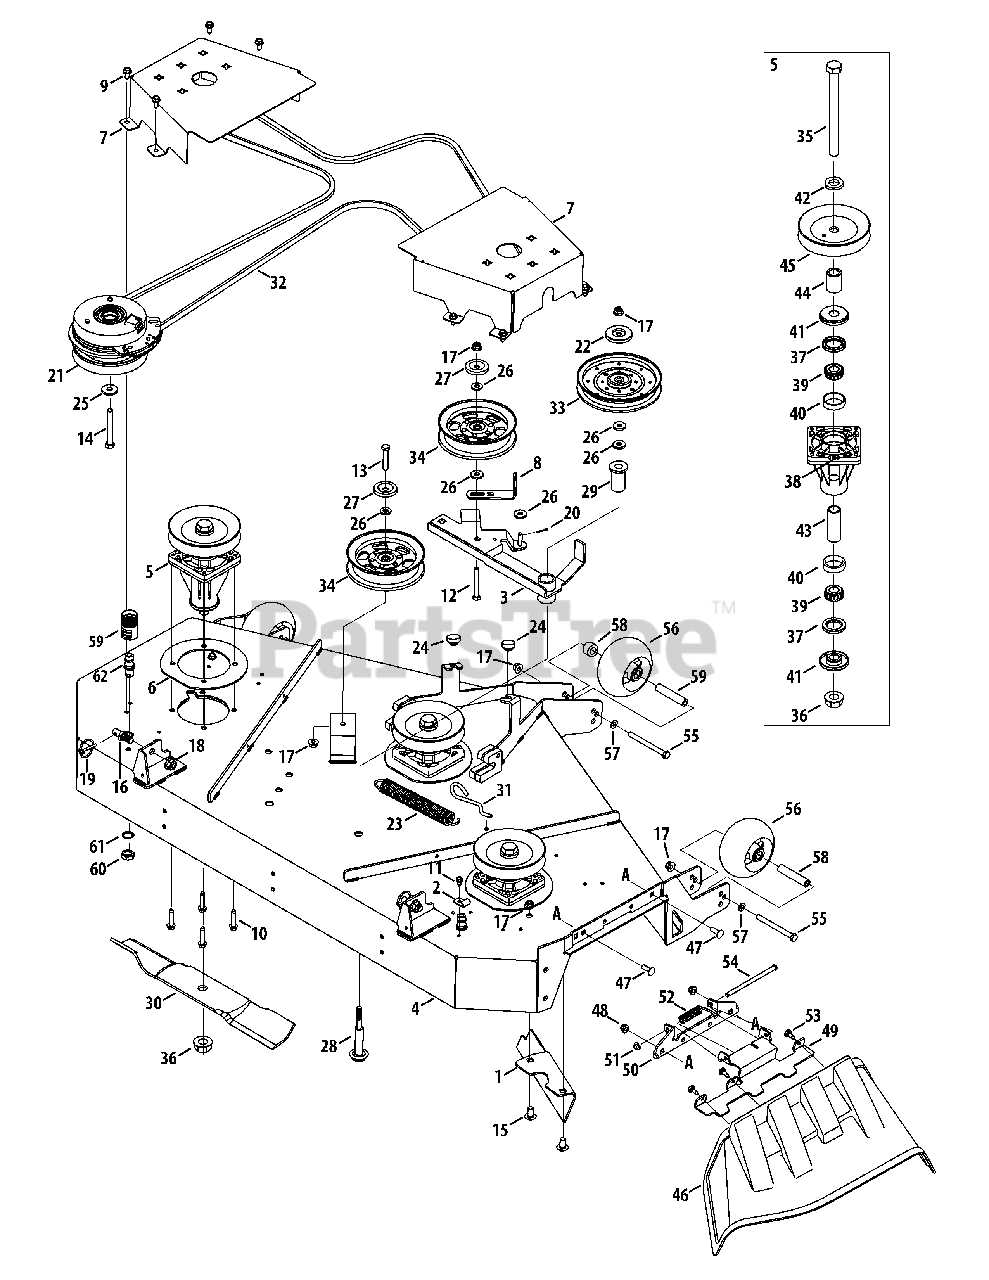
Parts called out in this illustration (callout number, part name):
2	Bracket, Hook Retainer
3	Deck Idler Assembly
4	60" Deck FAB - Yellow
4	60" Deck FAB - Black
5	Spindle Assembly
6	Spindle Reinforcement Plate - Yellow
6	Spindle Reinforcement Plate - Black
7	Belt Cover - Yellow
8	Bracket, Deck Keeper - Black
9	Hex Washer Screw, 5/16-18 x .750
10	Hex Washer Screw, 5/16-18 x 1.50
11	Hex Washer Screw, 1/4-20 x .500
12	Hex Cap Screw, 3/8-16 x 2.50
13	Hex Cap Screw, 3/8-16 x 2.00
14	Screw, 7/16-20 x 3.25
15	Carriage Screw, 3/8-16 x .75
16	Pin, Shoulder Lock, .500
17	Flange Lock Nut, 3/8-16
18	Flange Lock Nut, 1/2-13
19	Pin, Lynch x .1875
20	Cotter Pin 3/32" Dia. x .75 Lg.
21	Electric PTO Clutch
22	Pulley Cap
23	Extension Spring, 1.25 OD x 1.751
24	Rubber Bumper, 1.00 x .313
25	Flat Washer, .450 x 1.25 x .164
26	Flat Washer, .406 x .875 x .105
27	Pulley Cap
28	Shoulder Boult, .625 x 2.12, 3/8-16
29	Shoulder Spacer, 1.055 x .627 x 2.292
30	Blade, 21.00
30	Blade, Med-Lift Extreme
30	Blade, High-Lift Extreme
31	Deck Spring Rod
33	Idler Pulley, 6.00 Dia
34	Idler Pulley, 5.00 Dia.
35	Hex Cap Screw, 3/4-16 x 8.25
36	Nut, 3/4-16, Flangelock
38	Grease Fitting
39	Cone Bearing
40	Cup Bearing
41	Spindle Spacer
42	Spacer, .812 ID x .218 LG
43	Spacer, .78 x 1.00 x 2.895
44	Spacer, .792 x 1.20 x 1.628
45	V-Type Pulley
46	Discharge Chute Assembly
47	Carriage Bolt, 5/16-18 x 1.00
48	Flange Lock Nut, 5/16-18
49	Chute Bracket
51	Push Cap
52	Torsion Spring
53	Shoulder Screw, 1/4-20
54	Chute Rod
55	Hex Cap Screw, 3/8-16 x 4.0
56	Deck Ball Wheel, 5.0
57	Flat Washer, .406 x .875 x .059
58	Wheel Spacer
59	Water Nozzle Adapter
60	Hex Nut, M-16 x 1.5
61	Lock Washer, 17 x 23.8 x 1.95
62	Deck Water Nozzle
